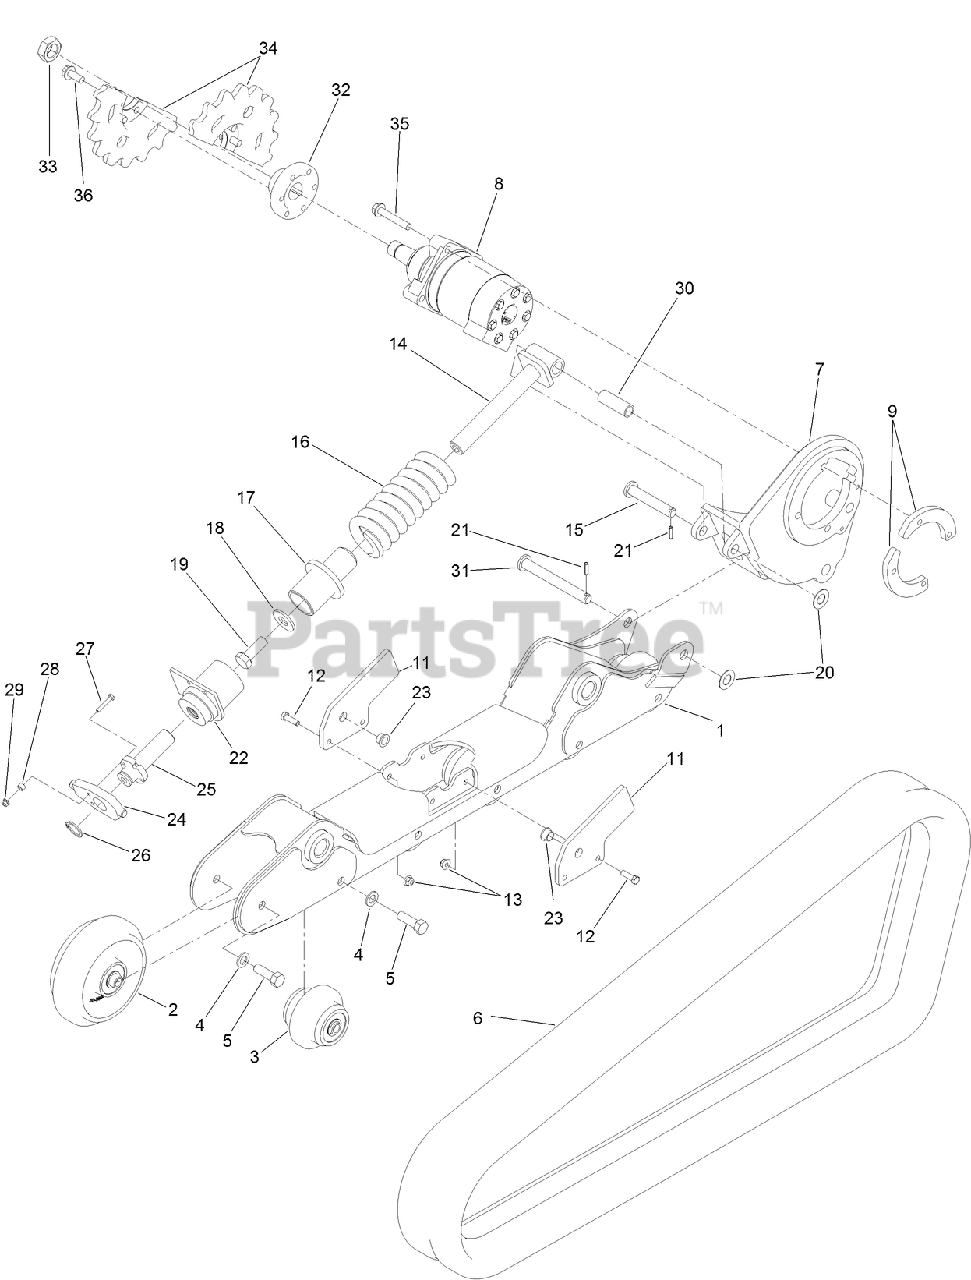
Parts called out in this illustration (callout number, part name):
1	FRAME-TRACK, RH
2	WHEEL-ASM TENSIONER
3	WHEEL-ASM CAMSO
4	WASHER-FLAT
5	SCREW-HH
6	TRACK-NARROW
7	MOUNT-MOTOR, RH
8	MOTOR-HYD
9	PLATE-MOUNTING, WHEELMOTOR
11	PLATE-EAR, INSIDE
12	SCREW-HH
13	NUT-HF, NI
14	TENSIONER-SPRING
15	PIN-TENSIONER
16	SPRING-COMPRESSION
17	GUIDE-TENSIONER
18	WASHER
20	WASHER-FLAT
21	PIN-SPRING
22	HOUSING-TENSIONER, RH
23	BUSHING-BELLCRANK
24	PLATE-PIVOT
25	SCREW-TENSIONER
26	RING-RETAINING, EXTERNAL
27	SCREW-HH
28	SPACER
29	NUT-HHF
30	SPACER-PIVOT
31	PIN-PIVOT
32	HUB-SPROCKET,
33	NUT-HEX
34	SPROCKET-18T,
35	SCREW-HF
36	SCREW-HHF
